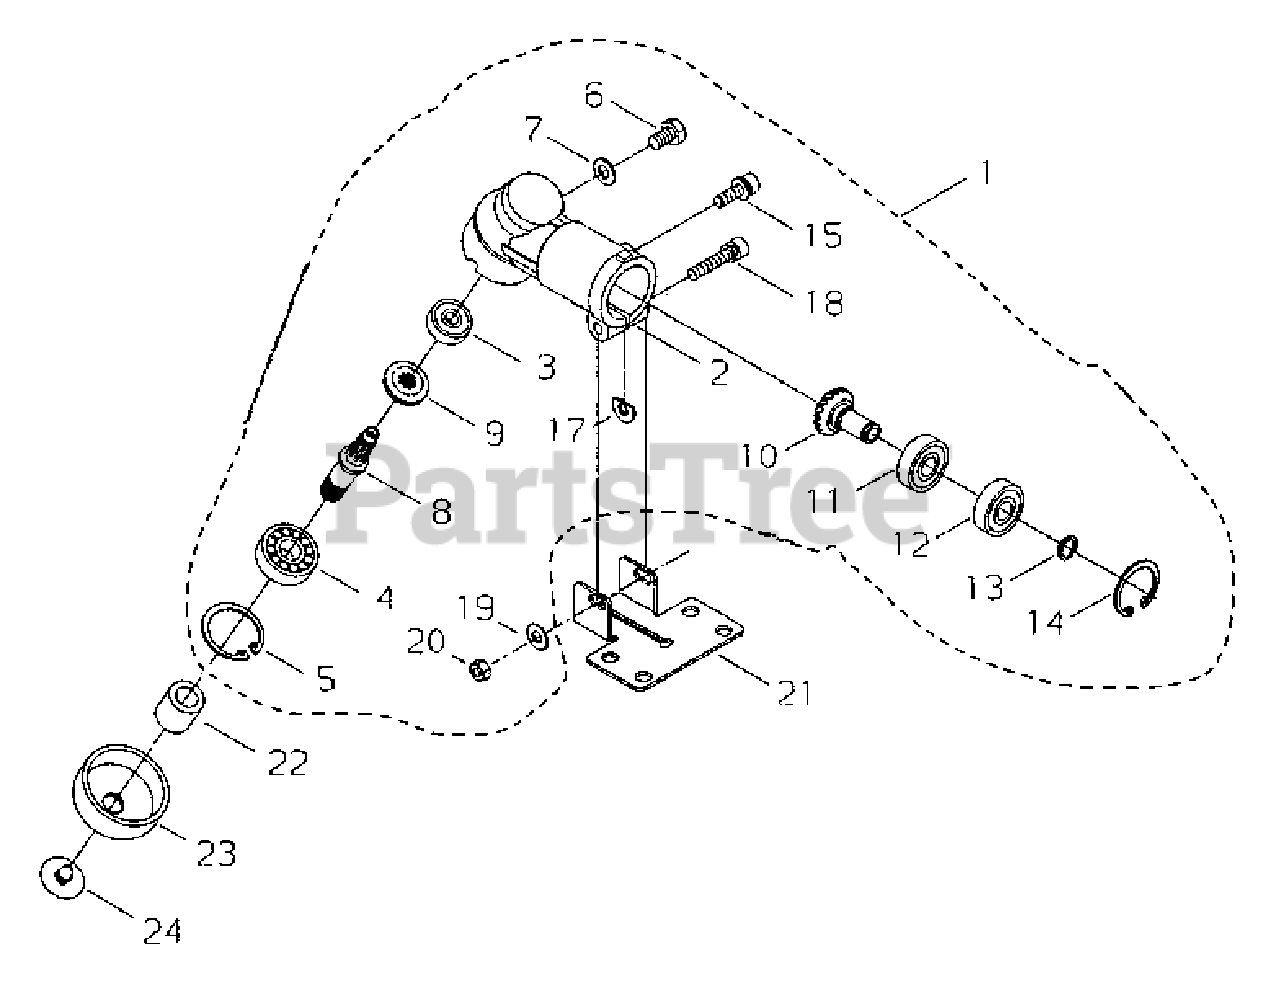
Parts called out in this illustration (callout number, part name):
1	GEAR CASE SUB ASSY
2	CASE, GEAR
3	BEARING, BALL - 626
4	BEARING, BALL - 6000
5	RING, RETAINING - 26
6	BOLT - 6X10
7	WASHER
8	GEAR - SHAFT
9	GEAR - BEVEL
10	GEAR - SHAFT
11	BEARING, BALL - 608
12	BEARING, BALL - 608ZZ
13	RING, RETAINING
14	RING, RETAINING - 22
15	SCREW - 5X16
17	SHIM
18	SCREW - 5X35
19	WASHER - 5
21	CLAMP - LOWER
22	COLLAR
23	HOLDER
24	CLIP
